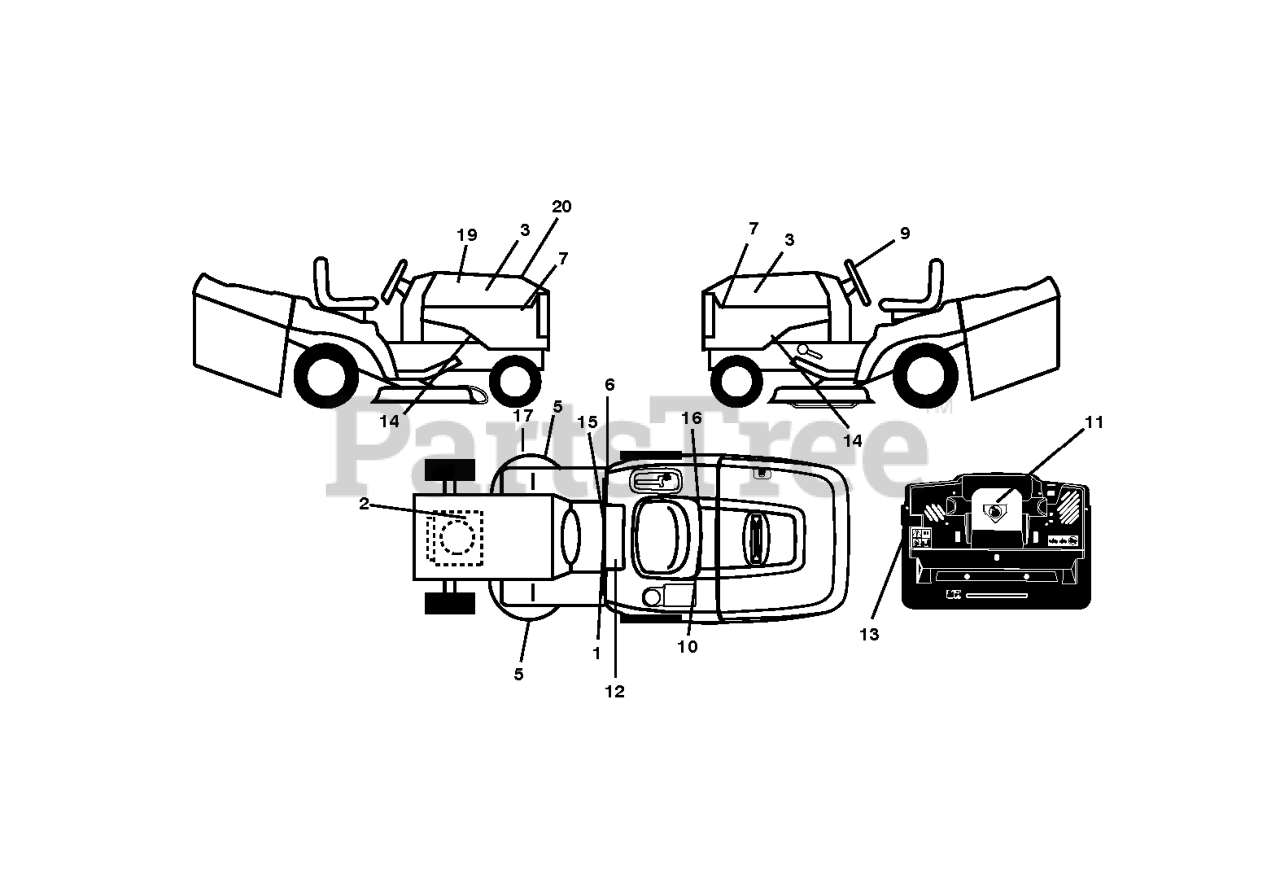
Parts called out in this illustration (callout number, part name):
1	LABEL
2	DECAL
3	DECAL.HOOD.NAMELOGO.HUSQ
6	Decal, Fender 100 DB/CE
9	DECAL.WHEEL.STRG.LGN.H
10	DECAL BTRY SYMBOLS
11	DECAL.INTERNATIONL.CUTFINGER
12	DECAL
13	DECAL
15	DECAL PARK BRAKE
16	DECAL.BYPASS.FENDER.CRD.LT.YT
20	DECAL.HOOD.TOP.INSERT.
